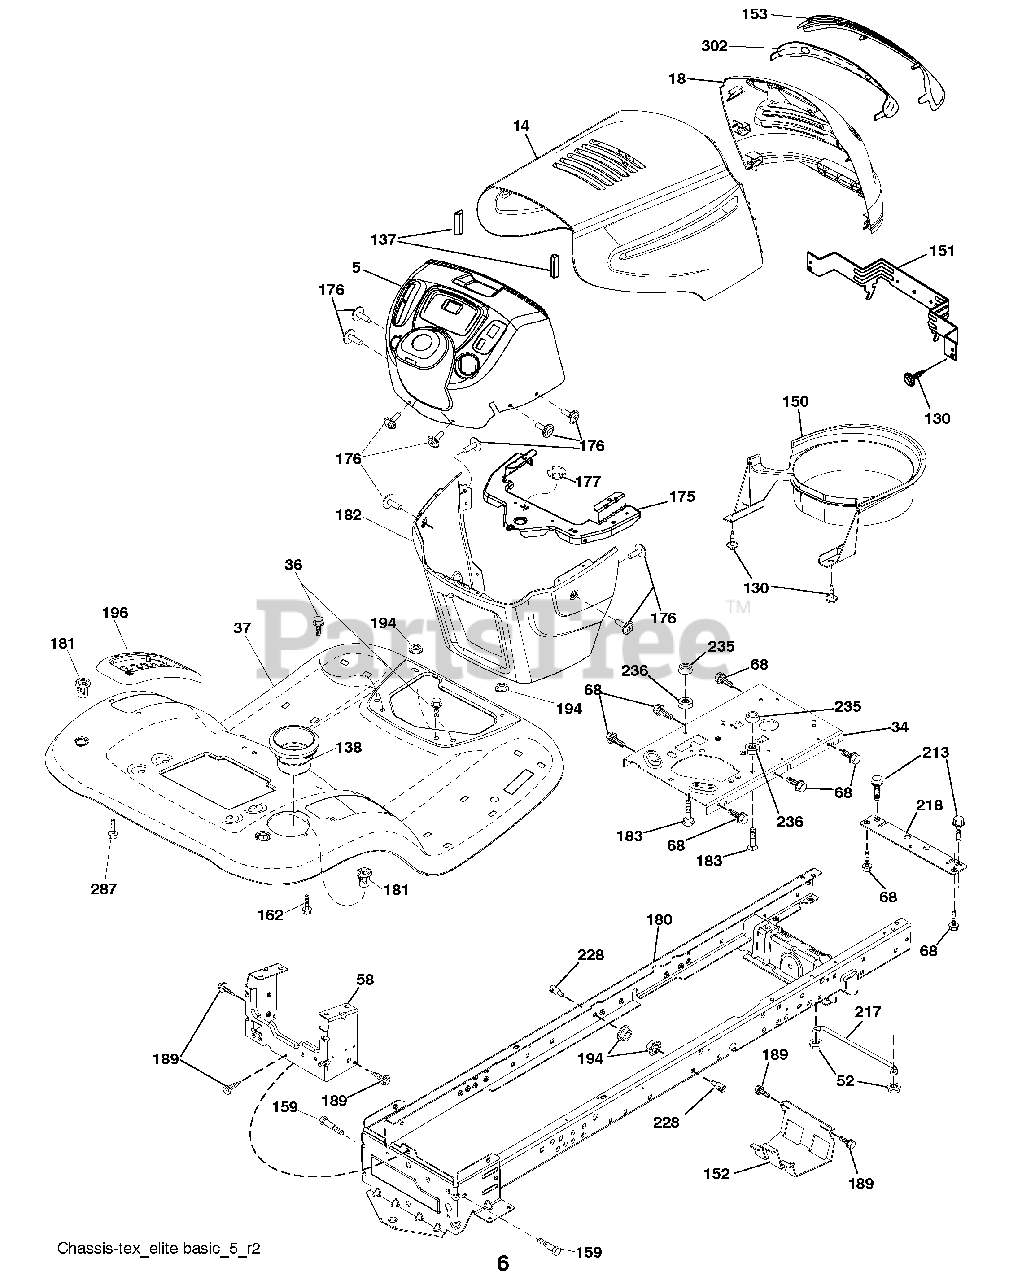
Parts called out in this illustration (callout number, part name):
14	Hood
34	Plate Engine
36	Screw 5/16-18 x 3/4
37	Fender
52	Nut Lock 5/16-18
58	Drawbar Upper
68	Screw Thdrol 5/16-18 x 1/2
130	Screw #10 x 0.750
150	Duct Heat Hood
151	Bracket Pivot
152	Shield Browning
159	Screw Hexwsh Thdrol 3/8-16 x 3/4
162	Screw Hex Wsh Hi-Lo 1/4 x 1/2
176	Screw 10-24 x 5/8 Wshd Qdrx
177	Bushing Steering
181	Bushing Mtg. Fender Crgo.
183	Bolt 5/16-18 x 1-1/4
189	Screw 5/16-18 x 3/4
194	Nut Lock Hex Flange 5/16-18
196	Console Asm. Deck Lift
213	Bolt 5/16-18 x 3/4
217	Rod Pivot Hood
218	X-Piece Hood Step
228	Stud Fastener
235	Spacer Fender
236	Nut Center Lock 5/16-18
287	Screw 1/4-20 x 3/8
302	Insert Lens Reflective
